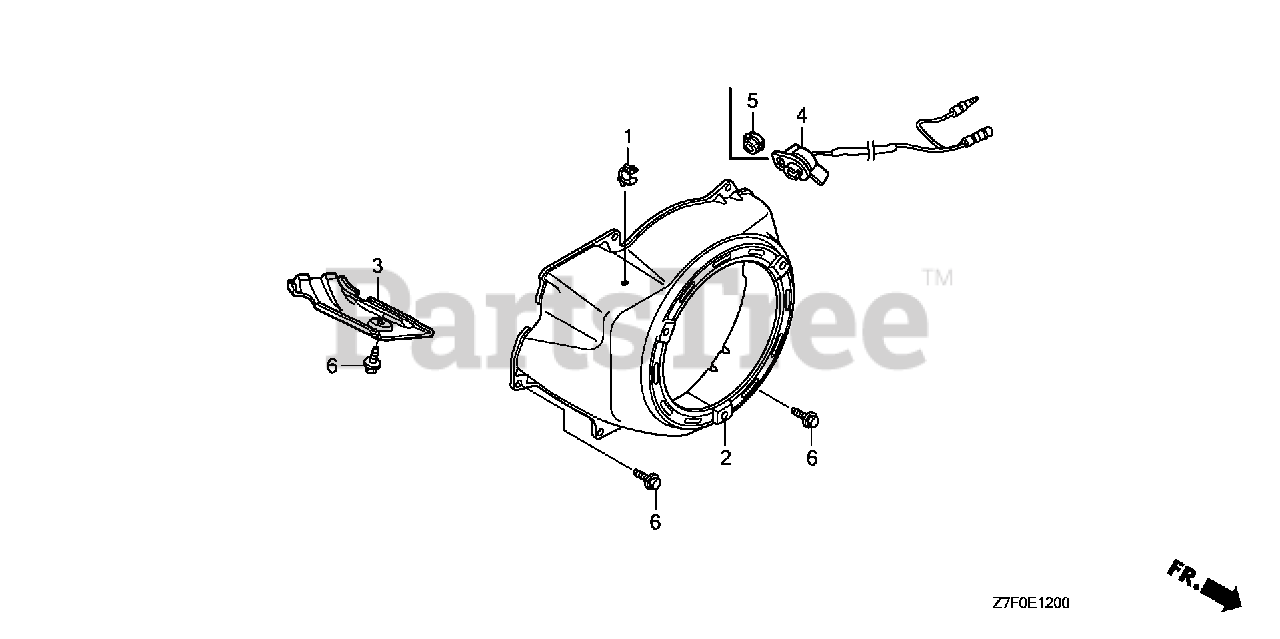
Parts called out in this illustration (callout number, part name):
1	CLIP, TUBE
2	COVER, FAN *NH1* (BLACK)
2	COVER, FAN *R280* (POWER RED)
4	SWITCH ASSY., ENGINE STOP
6	BOLT, FLANGE (6X12) (CT200)
